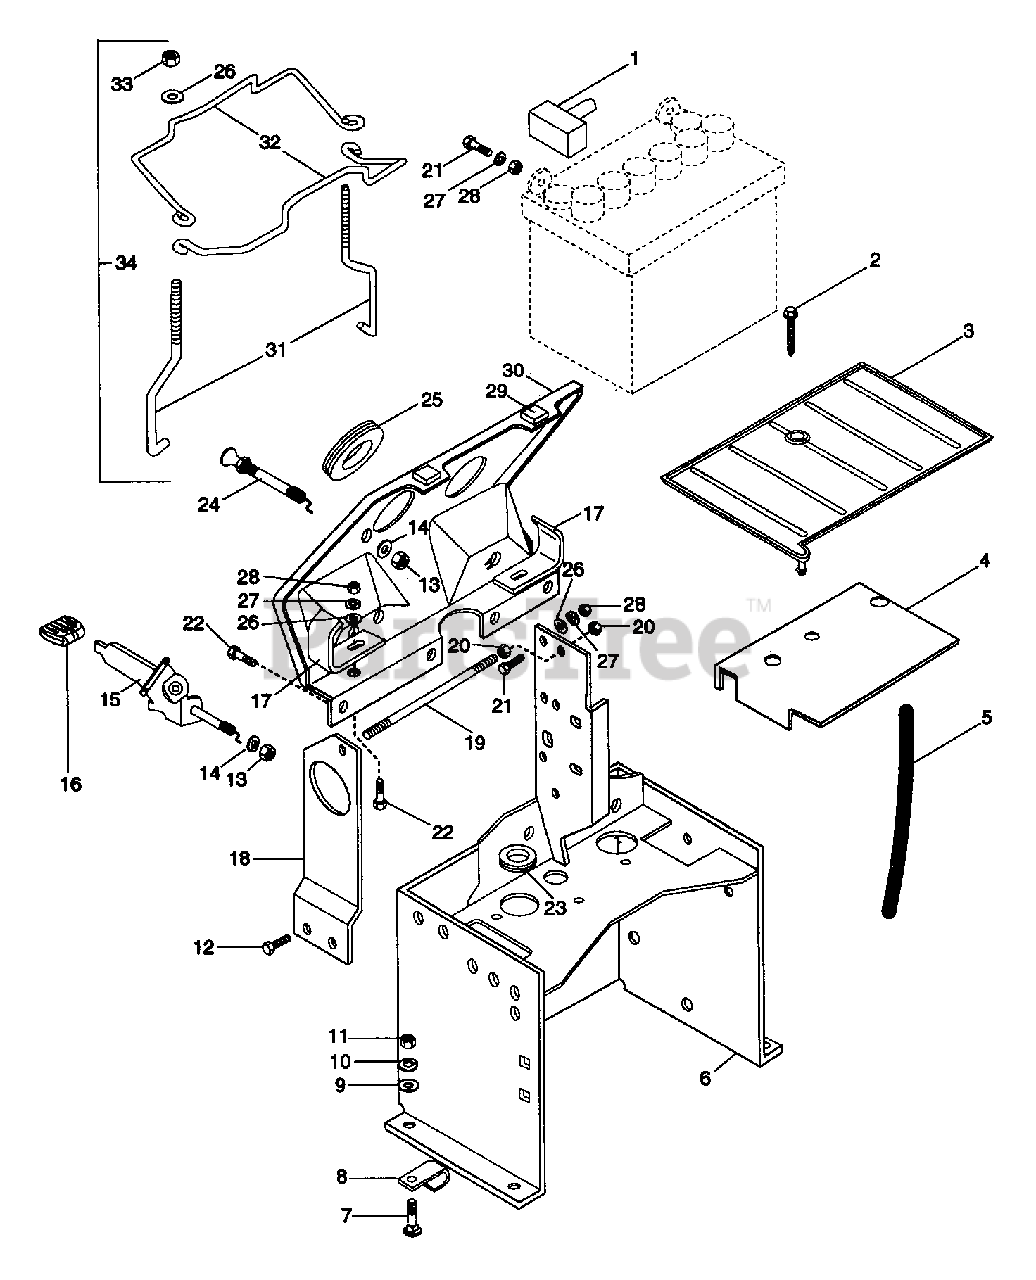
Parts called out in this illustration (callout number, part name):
1	INSULATOR
2	SCR-TAP 12-14X1.50 CROVH PL BT
3	BATTERY TRAY
4	BATTERY STAND
5	DRAIN HOSE
6	DASH SUPPORT PS
7	BLT-RDHDSQNK .31-18X.75 GR5 PL
8	J-CLAMP
9	WSHR-FL-STL.344X.688X.065PL
10	WSHR-LK .312X.097 PL HVY
11	NUT-HEX .312-18
12	SCR-TAP .250-20X.50 HXSLHDPL
13	NUT-HEX 10-24 PL
14	WSHR-LK-EXT #10 ID X .022
15	THROTTLE CONTROL
18	HOUR METER MOUNTING PLATE
19	BRACE ROD
20	NUT-LK-FLG .250-20 PL
21	BLT-HEX .25-20X.75 PL GR2
22	SCR-TAP 10-24X.375 HWH PL TR
23	GROMMET 1.0ID X 1.38 OD
24	CHOKE CONTROL
25	GROMMET
26	WSHR-FL-STL.281X.62X.065 PL
27	WSHR-LK .250X.077 HVY PL
28	NUT-HEX .250-20 PL
29	STOP
30	DASH
31	TIE DOWN
32	HOLD DOWN
33	NUT-LK-NYL .250-20 PL
34	BATTERY HOLD DOWN ASSEMBLY
